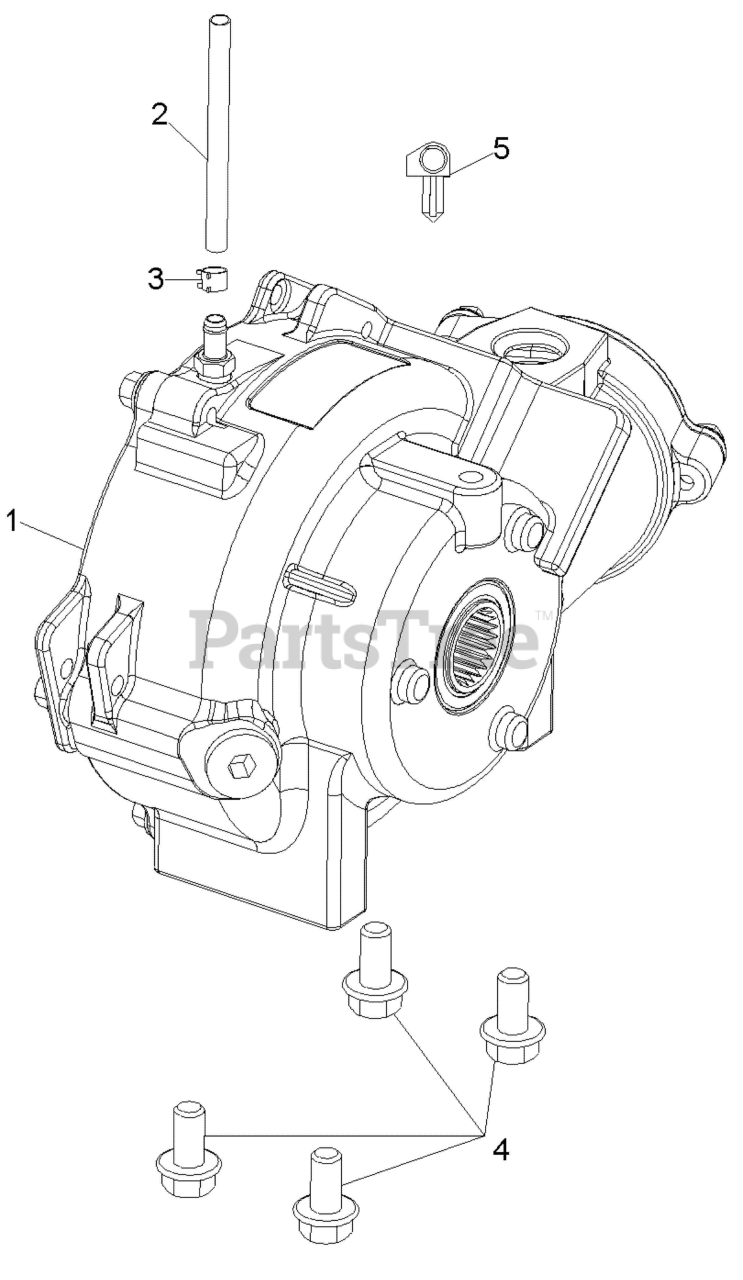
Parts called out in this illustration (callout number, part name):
1	ASM., FRONT GEARCASE 12 POCKET
2	LINE-BOOST,3/16 ID,76CM
3	CLAMP,HOSE(10)
4	BOLT-M10X1.5X20,HXFLG,W/PATCH
5	CLIP,ROUTING,.472 B.D.,HINGED
